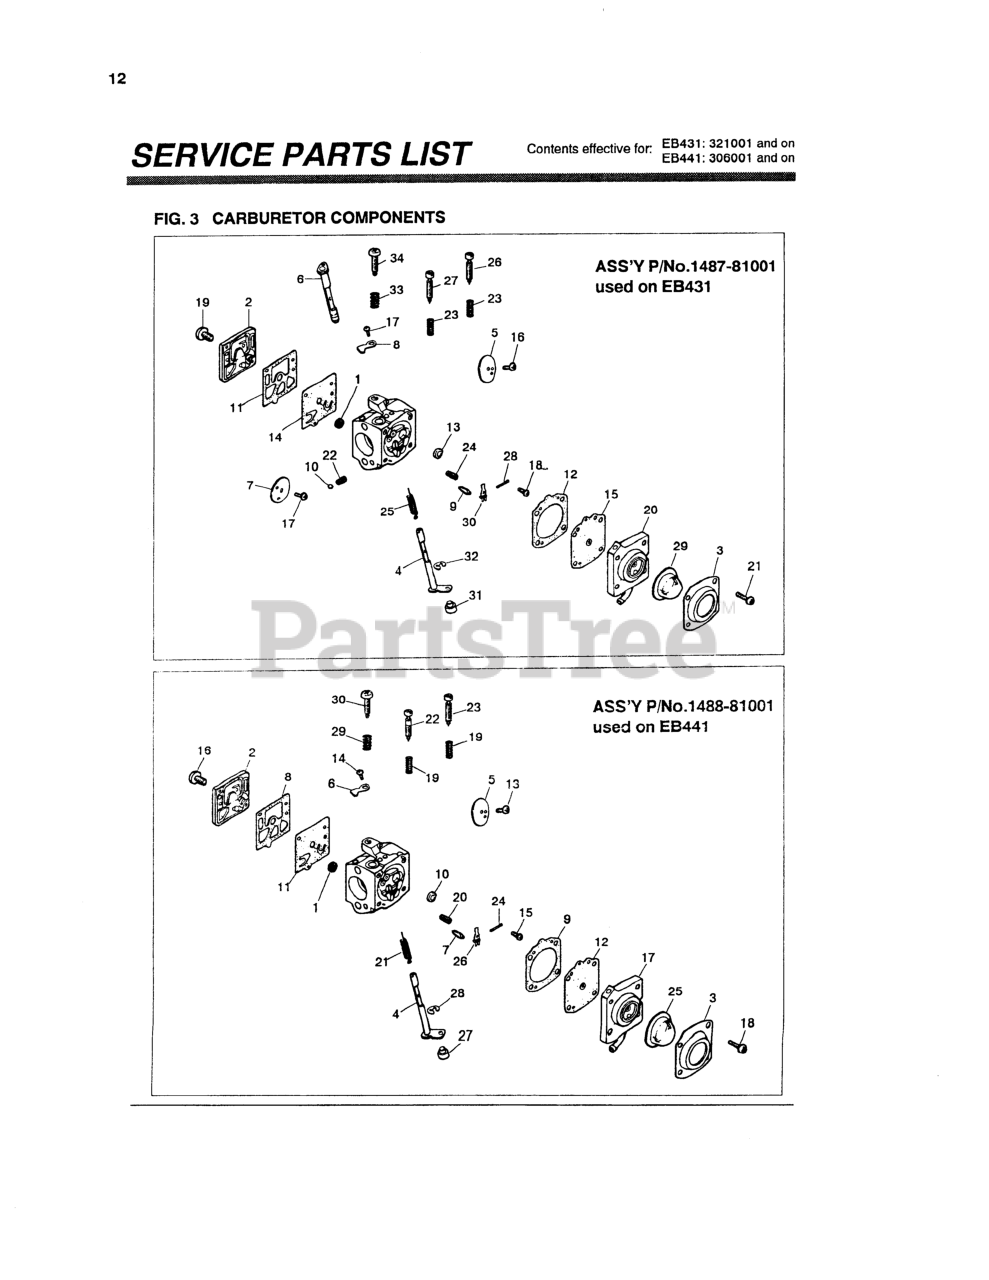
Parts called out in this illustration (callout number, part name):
2	COVER, PUMP
3	COVER, PUMP
4	SHAFT ASSEMBLY
6	SHAFT ASSEMBLY
7	VALVE, CHOKE
8	THROTTLE STOP
9	VALVE, INLET
10	BALL, FRICTION
11	KIT ONLY
12	KIT ONLY
13	PLUG, WELSH
14	KIT ONLY
20	BODY ASSY (RPLS 1491-81490)
21	SCREW (REPLACES 1491-81350)
22	SPRING
24	KIT ONLY
25	SPRING
26	NEEDLE (L)
27	NEEDLE (H)
28	PIN, METERING LEVER
29	PUMP, PRIMER
30	KIT ONLY
31	SWIVEL (USE -06040)
33	SPRING, IDLE
